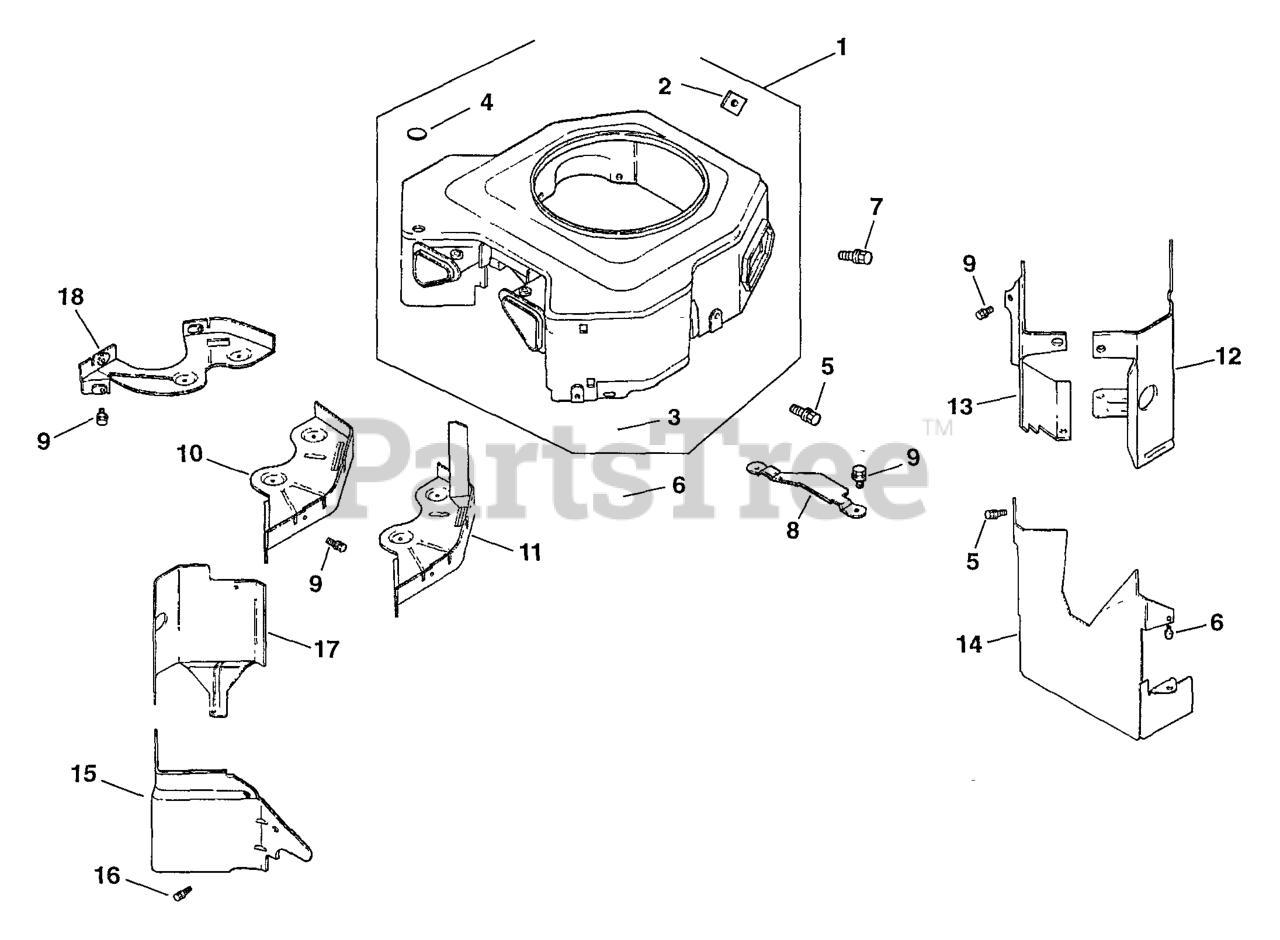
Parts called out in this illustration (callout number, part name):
2	Nut, Plastic
3	Nut, Plastic
4	Plug, Button 9/16"
5	Screw, Hex. Flange M5x0.8x16
6	Screw, Hex. Flange M5x0.8x20
7	Screw, Hex. Flange M5x0.8x16
8	Guard, Flywheel
9	Screw, Hex. Flange M6x1.0x16
11	Plate, Backing - #2 Side
12	Baffle, Cylinder Barrel - #2 Side
14	Baffle, Valley
16	Screw, Hex. Flange M5x0.8x10
17	Baffle, Cylinder Barrel - #1 Side
18	Plate, Backing - #1 Side
